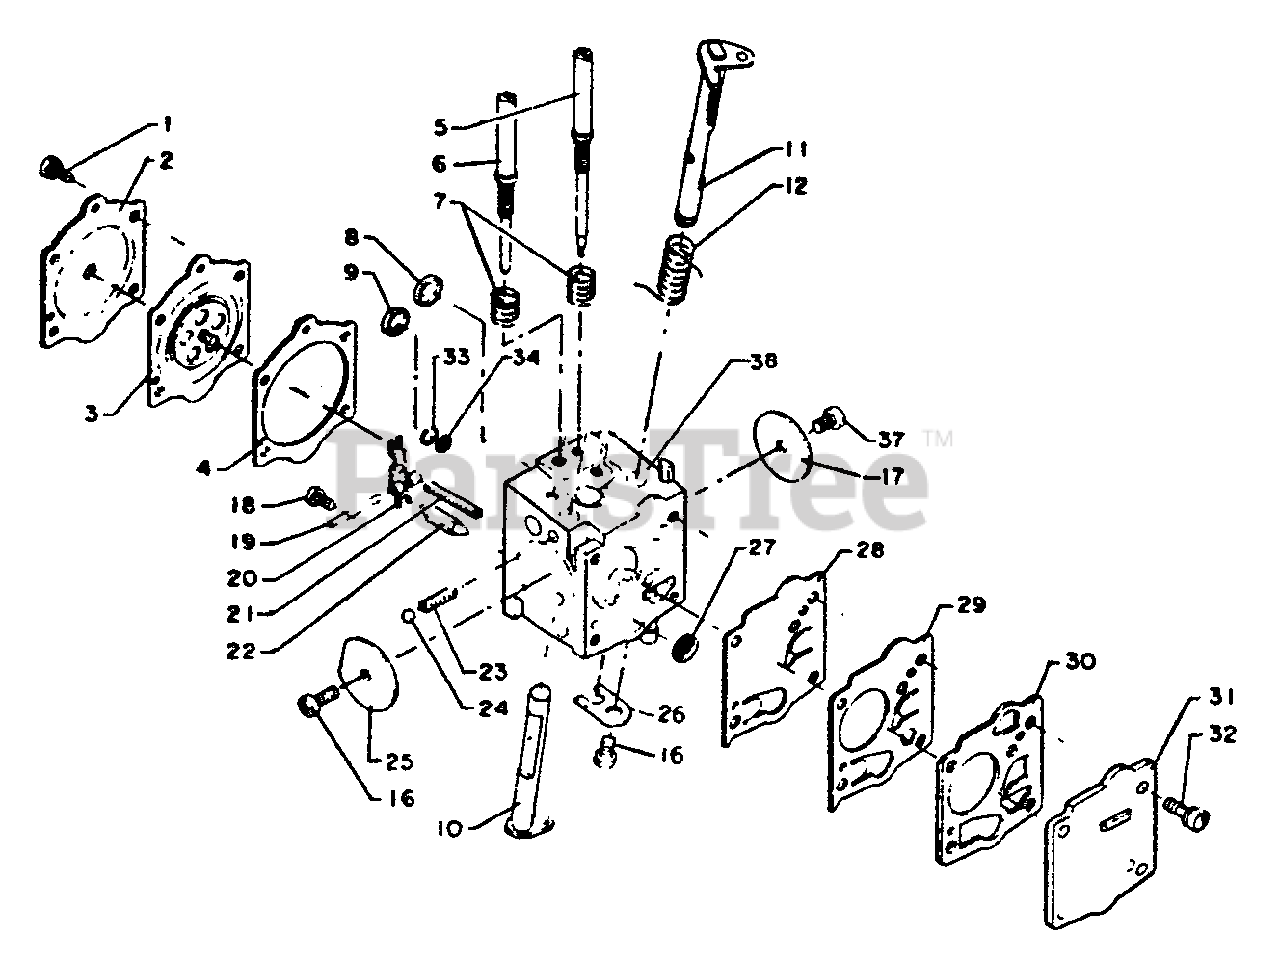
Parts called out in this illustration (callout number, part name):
1	SCREW
2	COVER, DIAPHRAGM
3	DIAPHRAGM, METERING
4	GASKET, METERING
5	NEEDLE, LOW SPEED
6	NEEDLE, HIGH SPEED
7	SPRING
8	PLUG, WELCH
9	PLUG, WELCH
10	SHAFT, CHOKE
11	SHAFT, THROTTLE
12	SPRING, THROTTLE RETURN
16	SCREW ASSY
17	VALVE, THROTTLE
18	SCREW, METERING LEVER PIN
19	PIN, METERING LEVER
20	LEVER, METERING
21	SPRING, METERING LEVER
22	VALVE, INLET NEEDLE
23	SPRING, CHOKE
24	BALL, CHOKE
25	VALVE, CHOKE
26	RING, RETAINING
27	STRAINER
29	DIAPHRAGM
31	COVER, PUMP
32	SCREW
33	RING, RETAINING
34	STRAINER
38	BODY, CARBURETOR
38	REPAIR KIT, CARBURETOR
38	DIAPHRAGM/GASKET KIT
